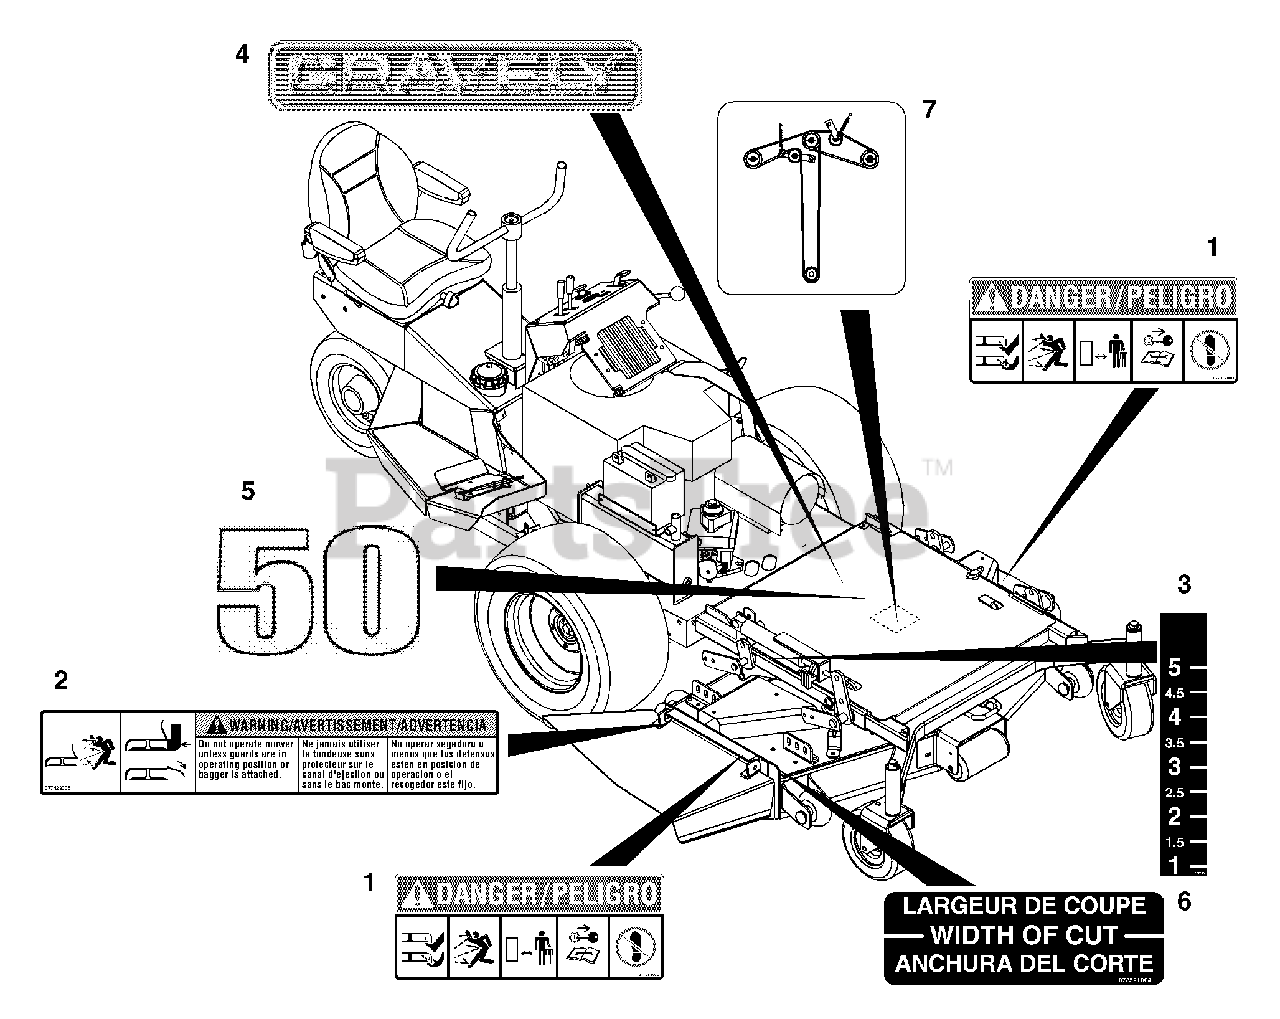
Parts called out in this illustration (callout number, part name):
1	Decal, Mower Pan Head Danger
2	Decal, Warning
3	Decal, Width of Cut
4	Decal-15" Gravely Logo
5	Decal, 50
5	Decal, 60
5	Decal, 72
6	Decal, Height of Cut
7	Decal, Belt Diagram
